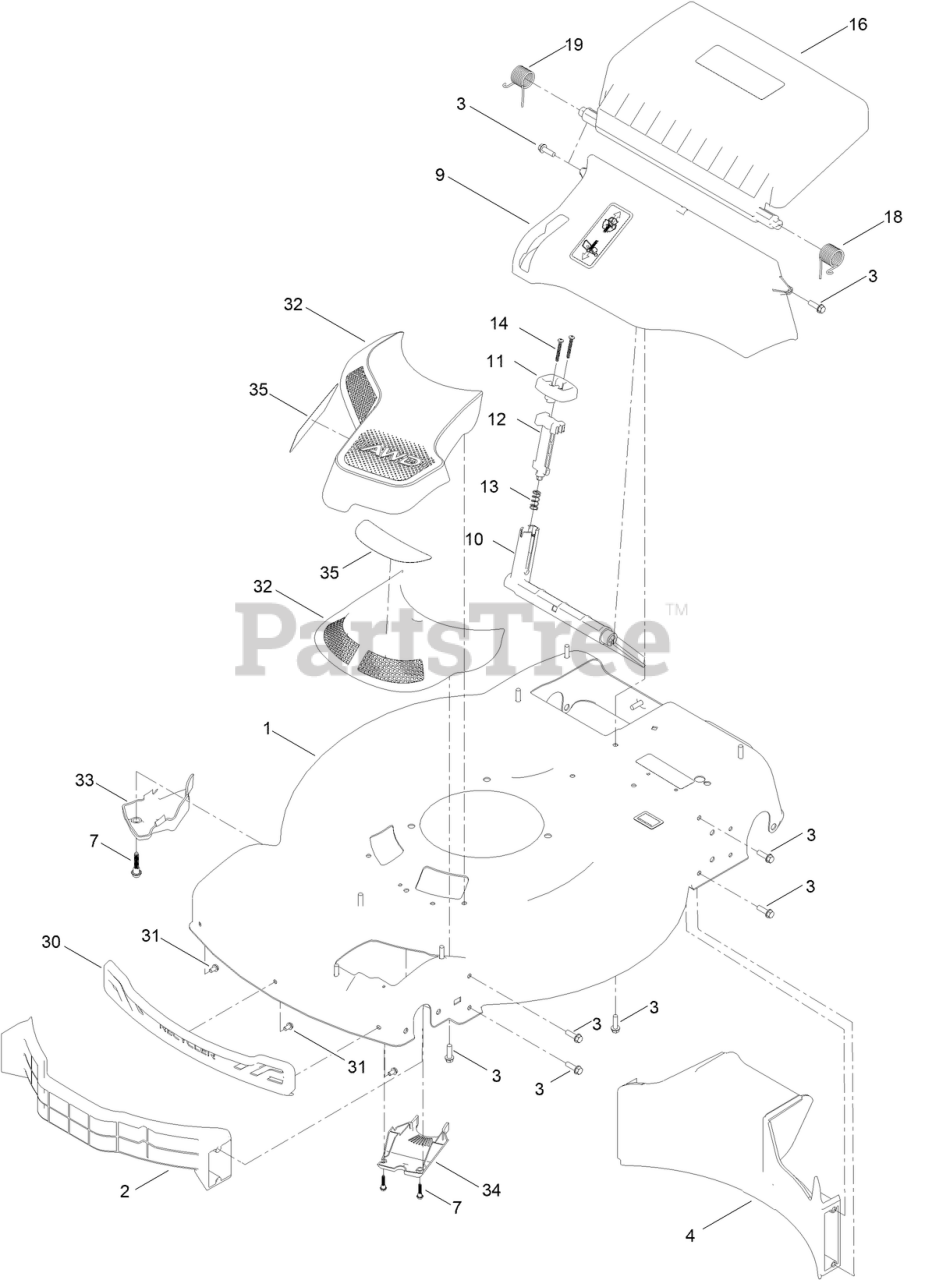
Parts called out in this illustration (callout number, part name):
1	HOUSING ASM
2	BAFFLE-FRONT, DOMESTIC
3	SCREW-HWH
4	BAFFLE-REAR, RWD
7	SCREW-SHOULDER, HHF
9	ASM-CHUTE, IN MOLD
10	DEFLECTOR-RECYCLE
11	KNOB-RECYCLE
12	LATCH-RECYCLE
13	SPRING-COMPRESSION
14	SCREW-PPH
16	ASM-REAR DOOR, IN MOLD
18	SPRING-TORSION, LH
19	SPRING-TORSION, RH
30	BUMPER-FRONT
31	SCREW-PLASTIC, HWH
32	ASM-INTAKE, AWD
33	COVER-INTAKE, BOTTOM
34	COVER-BELT, LOWER (AWD)
